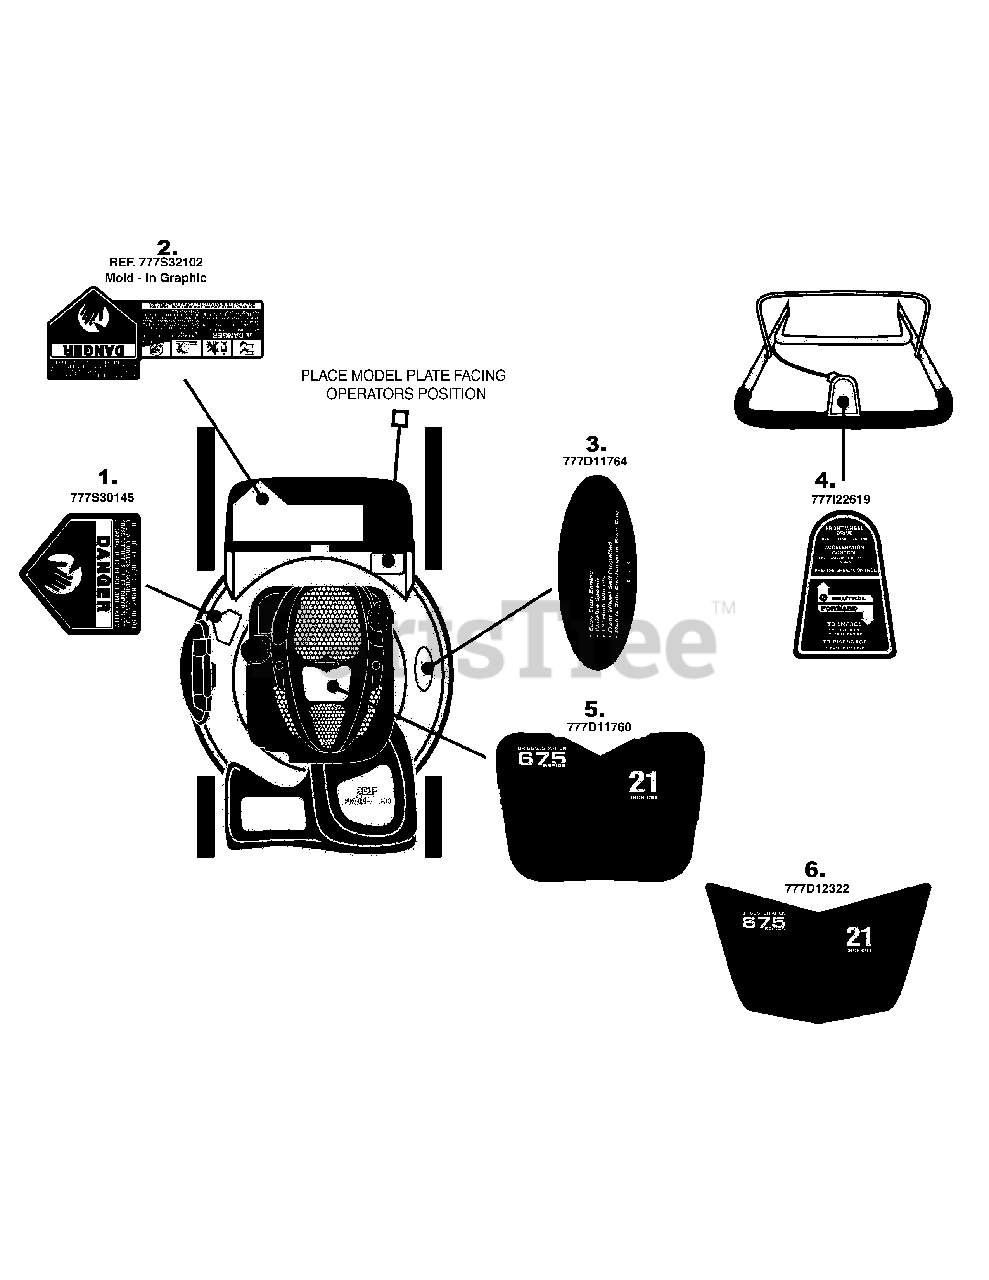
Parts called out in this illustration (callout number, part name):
1	LABEL
2	LABEL
3	LABEL-MOWER YARD MAN FAST TRACK
4	LABEL-MOWER SQ LEVER
5	LABEL-MOWER SHROUD YARD MAN 21"
6	LABEL-MOWER SHROUD YARD MAN 21"
